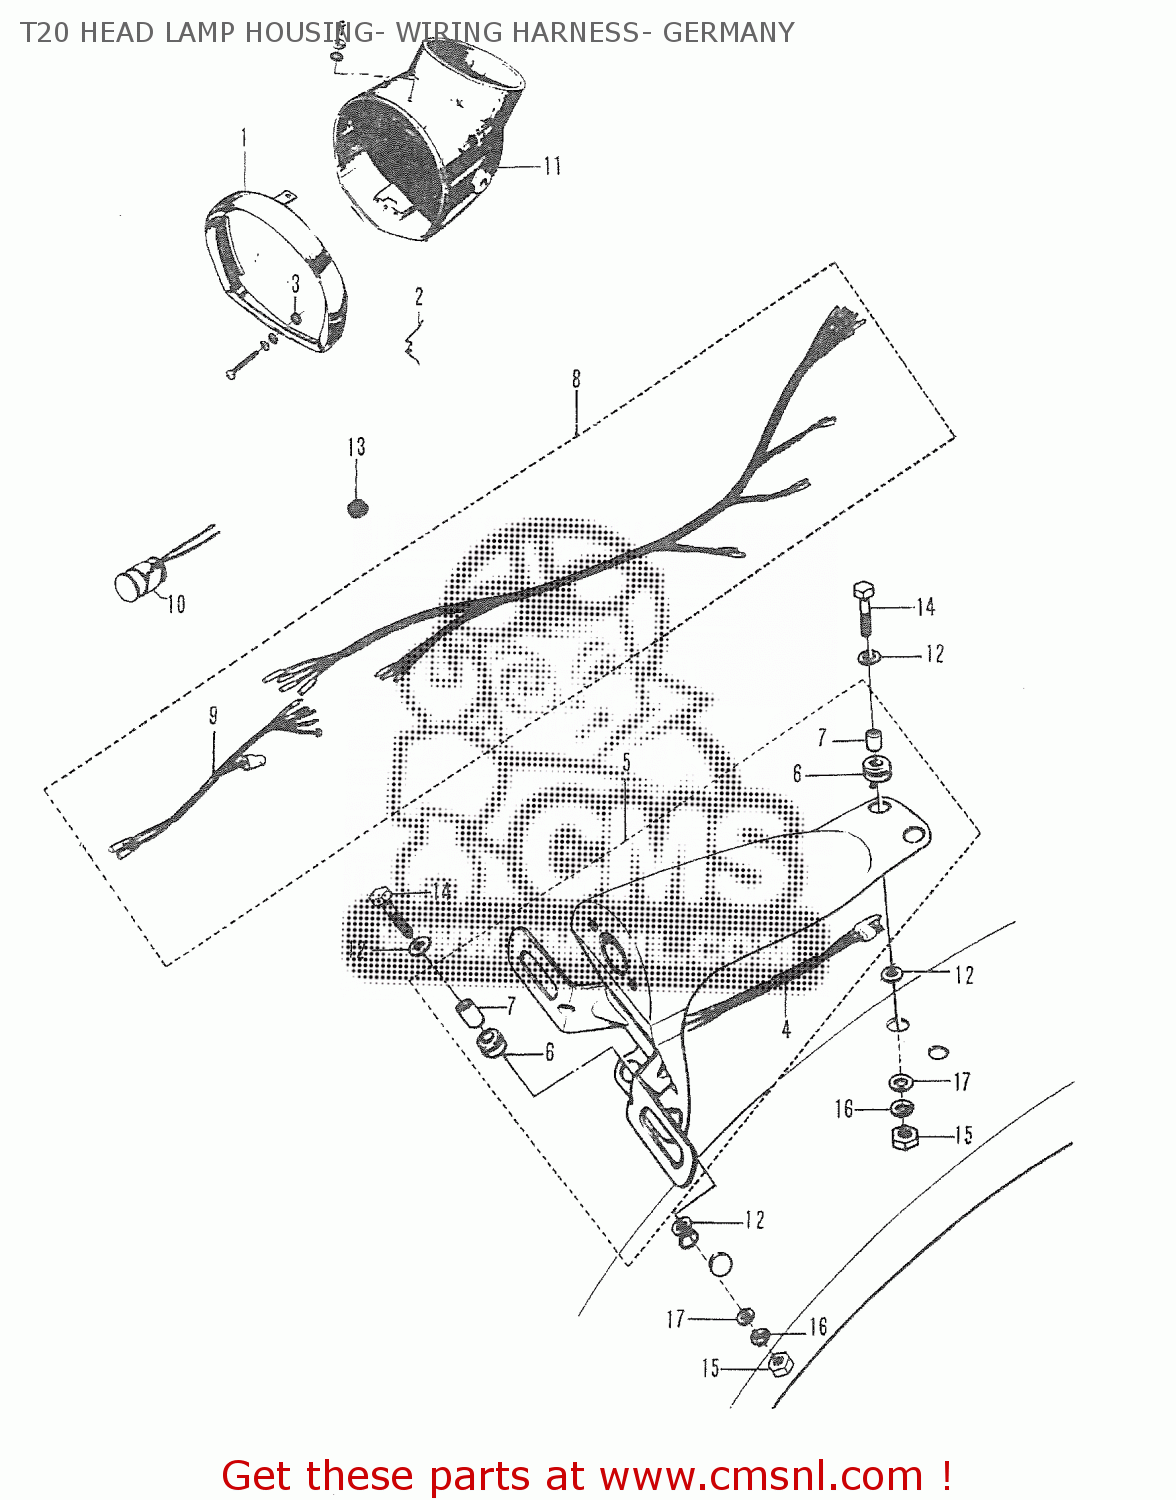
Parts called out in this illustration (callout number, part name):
1	HEAD LAMP RIM
2	SPRING,HEAD LA
3	HEAD LAMP FITTING SPACER
4	TAIL/BRAKE LAMP WIRING HARNESS NO.2
5	TAIL/BRAKE LAMP BRACKET ASS'Y
6	CUSHION
7	SPACER,REAR COMBINATION LAMP
8	MAIN WIRING HARNESS ASS'Y
9	TAIL/BRAKE LAMP WIRING HARNESS
10	TURN SIGNAL RELAY
11	HEAD LAMP HOUSING
12	WASHER
13	GROMMET
14	HEXAGON BOLT
15	HEXAGON NUT
16	LOCK WASHER
17	FLAT WASHER
